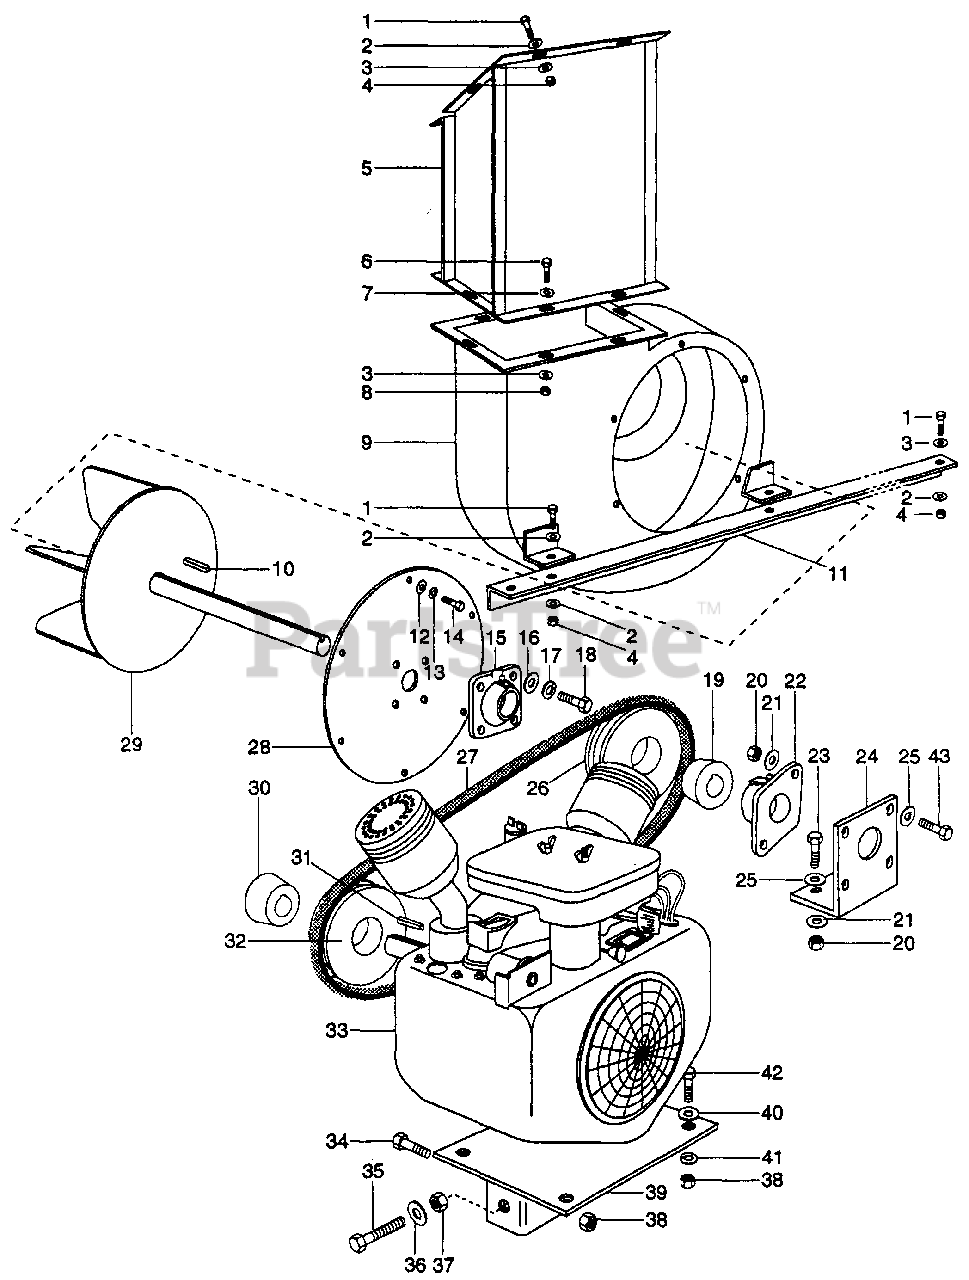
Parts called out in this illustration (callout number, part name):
1	BLT-HEX .38-16 X 1.00
2	WSHR-FL-STL .38 X 1.50 X .125 PL
3	WSHR-FL-STL .38 X .875 X .083 PL
4	NUT-LK TOP .375-16 GR C PL
5	DISCHARGE CHUTE WELDMENT
6	BLT-HEX .31-18 X 1.00 PL GR 5
7	WSHR-FL-STL .344 X .688 X .065
8	NUT-LK-TOP .312-18 GR C PL
9	BLOWER WELDMENT
10	KEY STR .38 X 2.0 X .38
11	BLOWER SUPPORT BEAM
12	WSHR-FL-STL .312 ID HEAVY PL
13	WSHR-LOCK .312 ID HEAVY PL
14	BLT-HEX .31-18 X .75 PL GR 5
16	WSHR-FL-STL .469 X .937 X .065 PL
17	WSHR-LOCK .438 X .133 HVY
18	BLT-HEX .44-14 X 1.38 GR 5
19	DRIVEN SHEAVE BUSHING
20	NUT-LK-CTR .50-13
21	WSHR-FL-STL .531 X 1.062 X .095 PL
22	BRG 2 BLT
23	BLT-HEX .50-13 X 1.50 PL GR 5
24	BEARING HOLDER
25	WSHR-FL-STL .563 X 1.37 X .109 PL
26	PLY - V 2G 3V 6.5 TAPER LOCK
27	V-BELT MATCHED SET OF TWO
28	FAN COVER WELDMENT
29	FAN
30	DRIVE SHEAVE BUSHING
31	KEY-SQ .25 X 1.25 X .25 SAE
32	PLY - V 2G 3V 5.5 TAPER LOCK
33	ENGINE-KOHLER 18 HP # 24653
34	BLT-HEX .38-16 X 1.25 PL GR 2
35	BLT-HEX .50-13 X 5.00 PL GR 2
36	WSHR-FL-STL .511 X 1.44 X 1.25 PL
37	NUT .50-13 PL
38	NUT-LK .375-16 X 1.25 PL GR 2
39	ENGINE SUBPLATE WELDMENT
40	WSHR-FL-STL .406 X .812 X .065 PL
41	WSHR-FL-STL .406 X 1.000 X .105
42	BLT-HEX .38-16 X 1.25 GR 5
43	BLT-HEX .50-13 X 1.75 PL GR 5
